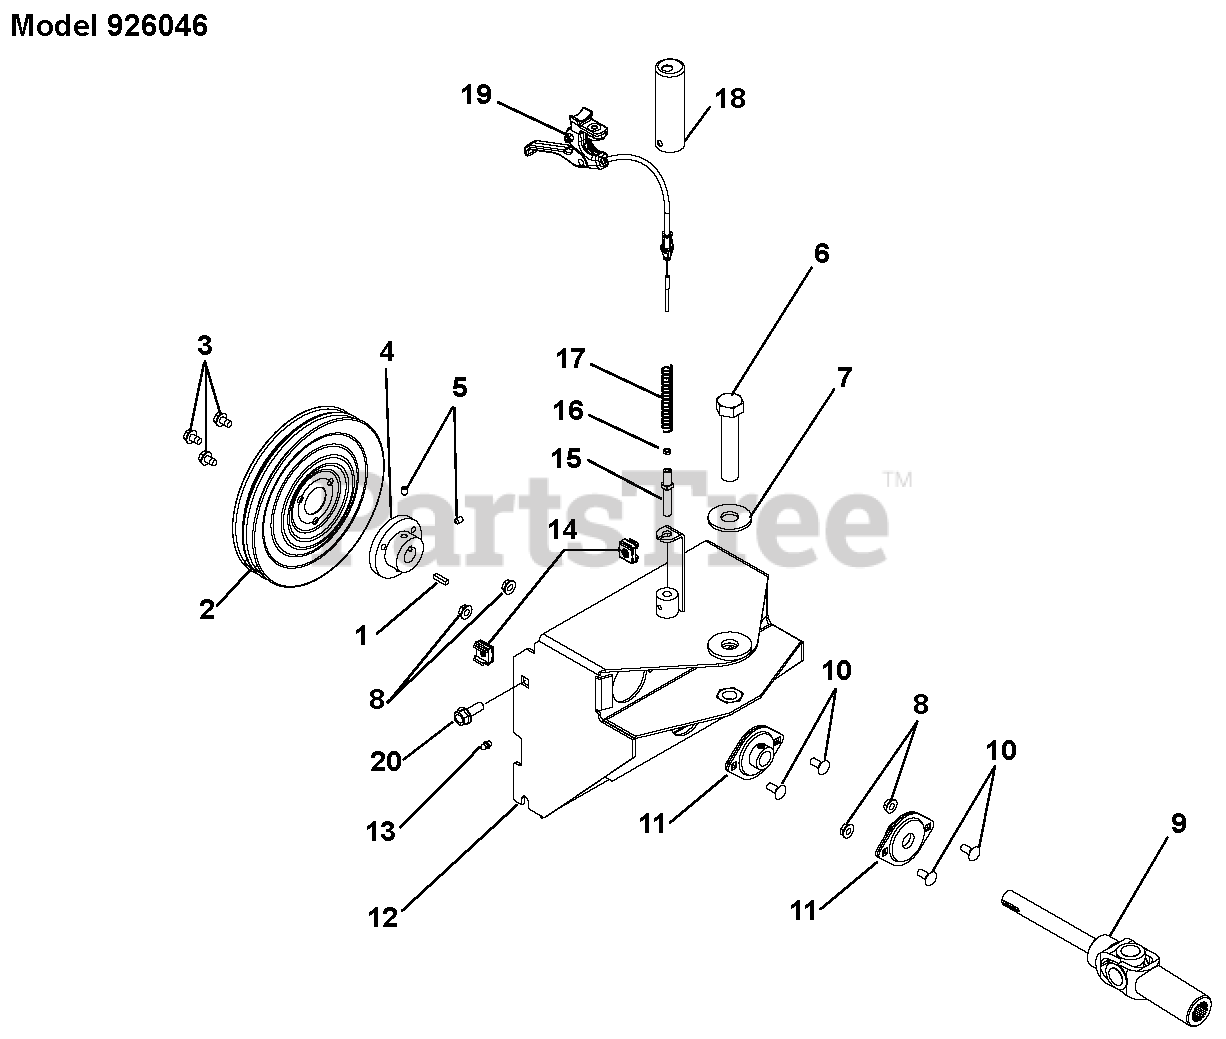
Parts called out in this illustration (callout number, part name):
1	Key, Square .188 x .75 x .188
2	Pulley, Attachment
3	Screw, Tapping Hex Washer Head Thread Rolling .31-18 x .50
4	Hub, Pulley
5	Screw, Set Socket Head Cup Point Nylon Oil Hardened .25-20 x .38
6	Bolt, Hex .75-16 UNF x 3.75
7	Washer, Flat Steel .812 x 2.00 x .148
8	Nut, Locking Top Flange .31-18
9	Driveline
10	Bolt, Round Head Square Neck .31-18 x .75
11	Bearing
12	Mounting Frame
13	Fitting, Lube .25-28 x .256
14	Nut, Retainer .38-16
15	Pin, Swing
16	Nut, Hex 10-24
18	Cap, Vinyl
19	Cable, Remote Brush Lock
20	Bolt, Serrated Hex Washer Head .38-16 x .75
